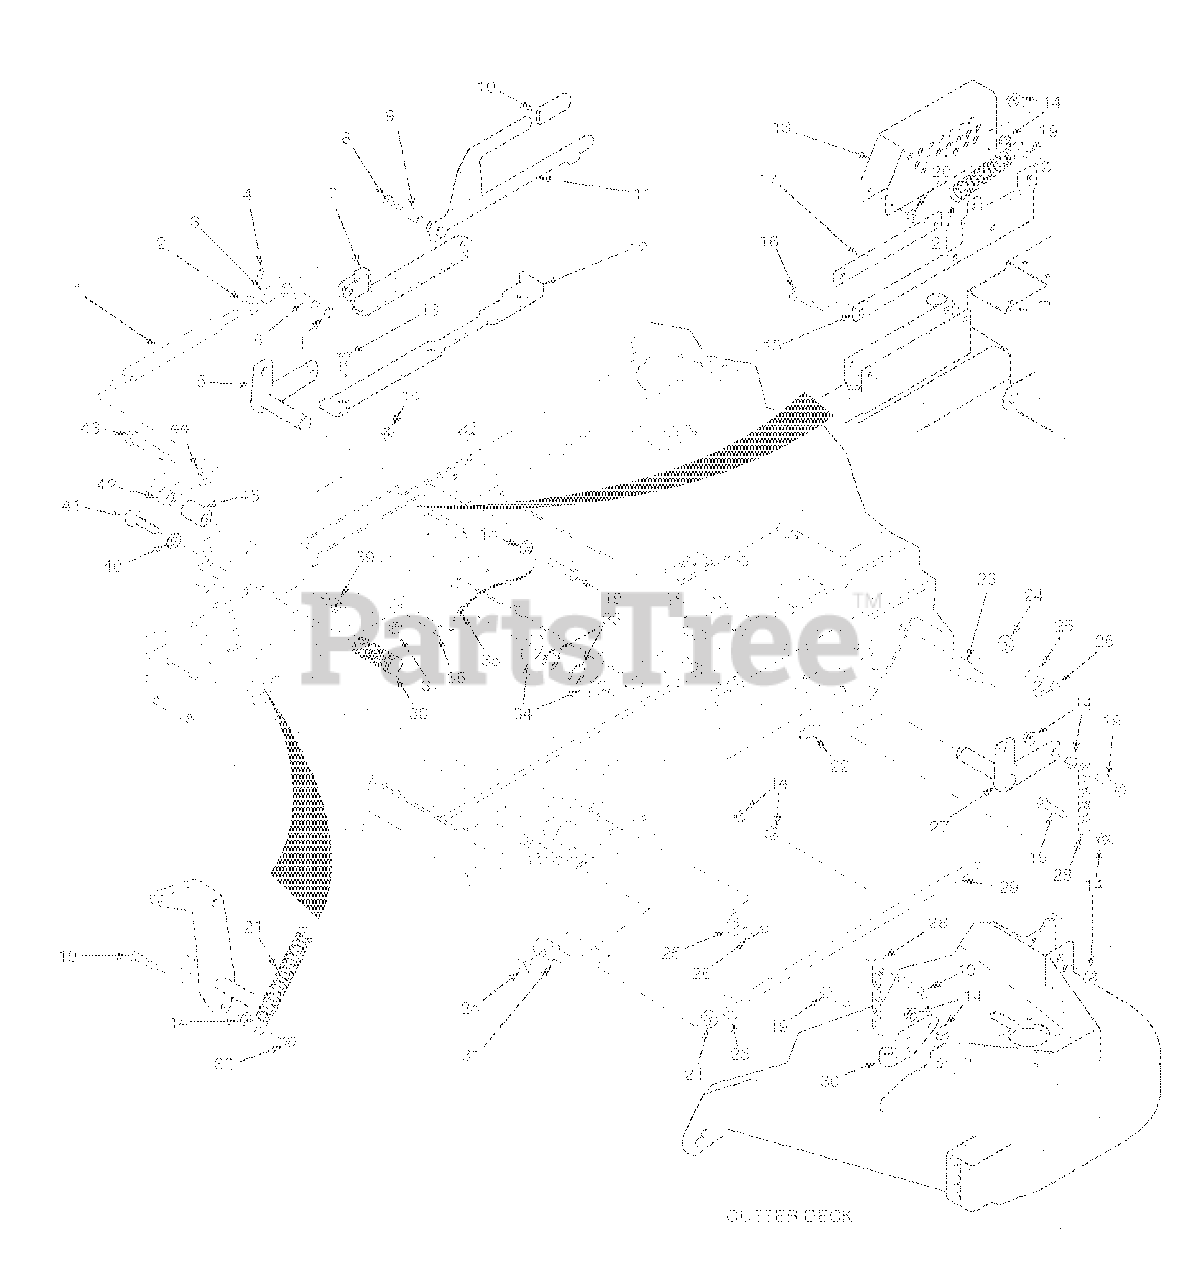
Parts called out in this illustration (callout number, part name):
1	Link, Deck Lift
2	Nut, Jam 1/2-20 LH
3	Rod End, Female - 1/2-20 LH
4	Ring, Retaining 1/2" External "E"
5	Bellcrank Weldment, RH Rear
6	Pin, Decklift
7	Slide Weldment, Height Adjustment
8	Bolt, Shoulder 1/2 x 3/4"
9	Bushing, .502 ID.
10	Grip, Deck Latch
11	Deck Latch
12	Lockplate, Decklift
13	Screw, Cap 5/16-18 x 3" FHHS
14	Nut, Hex Serrated Flange 3/8-16
15	Guide, Long
16	Bolt, Carriage 5/16-18 x 1"
17	Guide, Short
18	Bracket, Cutting Height Adjustment
19	Bolt, Hex Head 3/8-16 x 1-1/2"
20	Nut, Hex Serrated Flange 5/16-18
21	Spring, Helper
22	Grease Fitting
23	Swivel Joint, LH
24	Nut, Hex 5/8-11
25	Flatwasher, 5/8" (.656 x 1.312 x .095)
26	Cotter Pin, 3/16 x 1"
27	Bellcrank Weldment, LH Rear
28	Chain
29	Stud, 5/8-11 x 26.0"
30	Lever Assembly, Deck Level
31	Swivel Joint, RH
32	Locknut, 3/8-16 Center Lock
33	Ring, Retaining 1" External "E"
34	Flatwasher, 1" (1.062 x 1.50 x .048)
35	Lanyard, Deck Height Pin
36	Ring Pin, 1/2 x 3.06"
37	Nut, 3/8-16 Elastic Stop
38	Foot Pedal, Height Adjustment
39	Nut, Hex Elastic Stop 1/2-13
40	Lockwasher, 5/8"
41	Capscrew, 5/8-11 x 1-1/2"
42	Rod End, Female - 1/2-20 RH
43	Bolt, Hex Head 1/2-13 x 3"
44	Nut, Jam 1/2-20 RH
45	Spacer, Decklift Pedal
